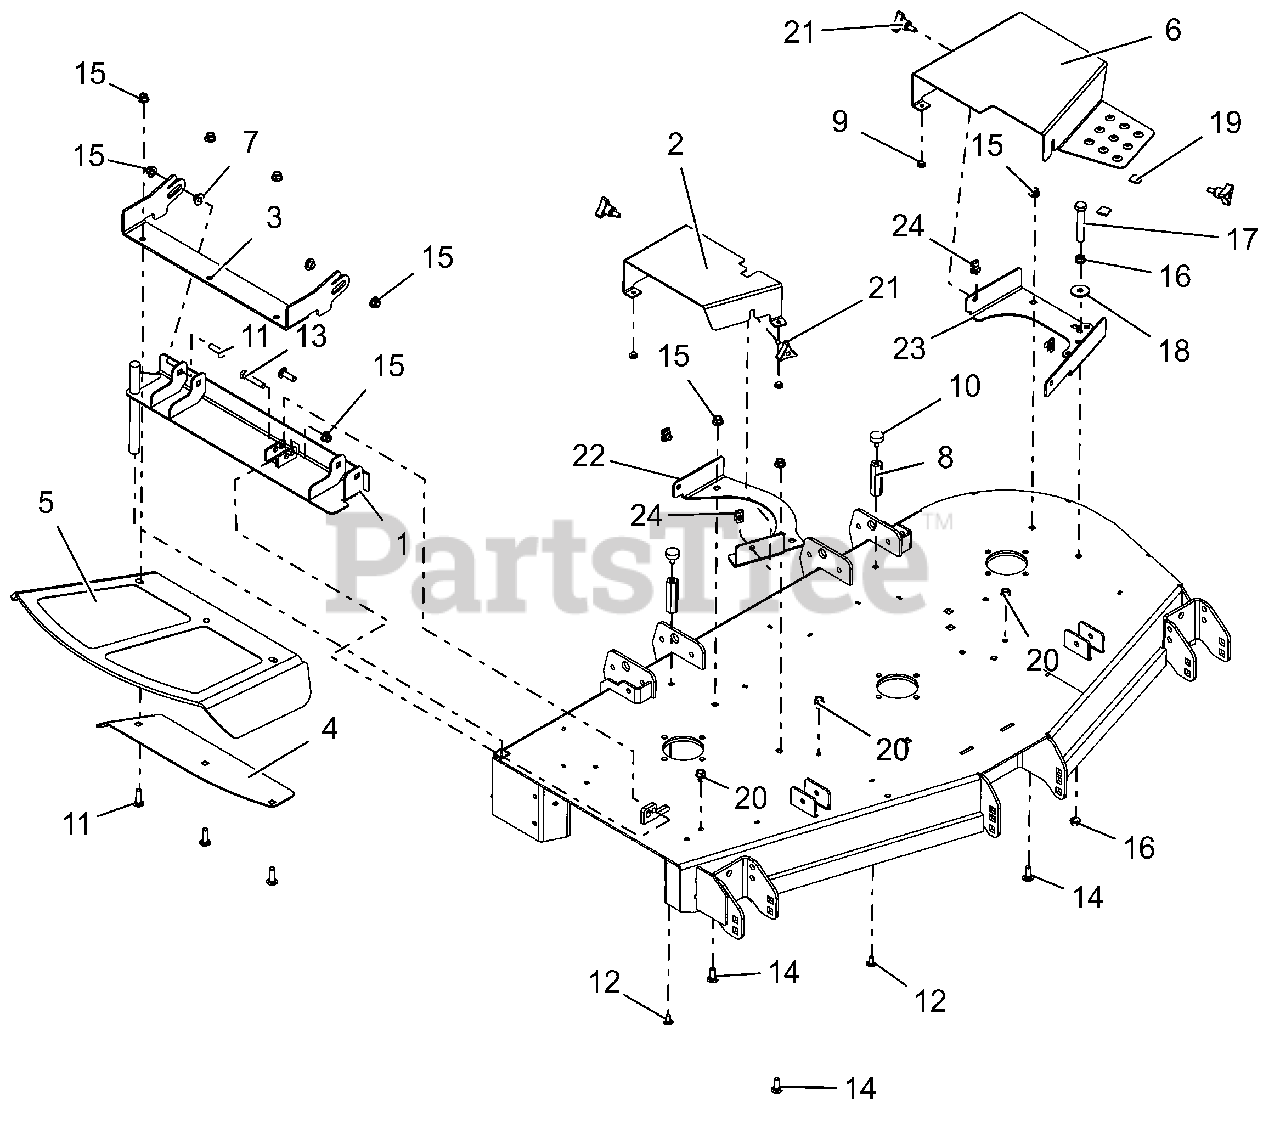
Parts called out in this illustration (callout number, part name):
1	48-60 DISCH CHT MTG WMT W/SAFE
2	PT148-152 DECK RH BELT GRD-RED
3	48-60" CHUTE MTG BRKT - RED
4	48-60 DISCH CHUTE CLMP PLT-RED
5	CHUTE,48-60" FRMD RUBBER DISCH
6	PT100 DECK LH BELT GUARD - RED
7	BSHG-FLG .385X.500X.875X.406
8	NUT, COUPLING .31-18 2.75 LG
9	BUMPER GROMMET
10	BUMPER, RUBBER
11	@BLT-RHDSSQNK .38-16X1.25 G5YZ
12	BLT-RDHDSQSHNK.31-18X.62 YZ-LK
13	@BLT-HEX .38-16X2.00 GR5 YWZC
14	@BLT-RDHDSQNK .38-16X1.00 G5YZ
15	@NUT-LK-NYL-FLG .38-16 YWZC
16	@NUT-SPNLK-FLG .375-16 YWZC
17	@BLT-HEX .50-13X3.00 GR5 YWZC
18	WSHR-FL-STL .406X1.375X.135 YZ
20	@SCR-TAP .38-16X.50 HWH TR YWZ
21	KNOB,WING STUD 5/16-18 X .75
22	BRKT, BELT GUARD RH MOUNTING (RED)
23	BRKT, BELT GUARD LH (RED)
24	NUT-CLIP RETAINER 5/16-18X.56
